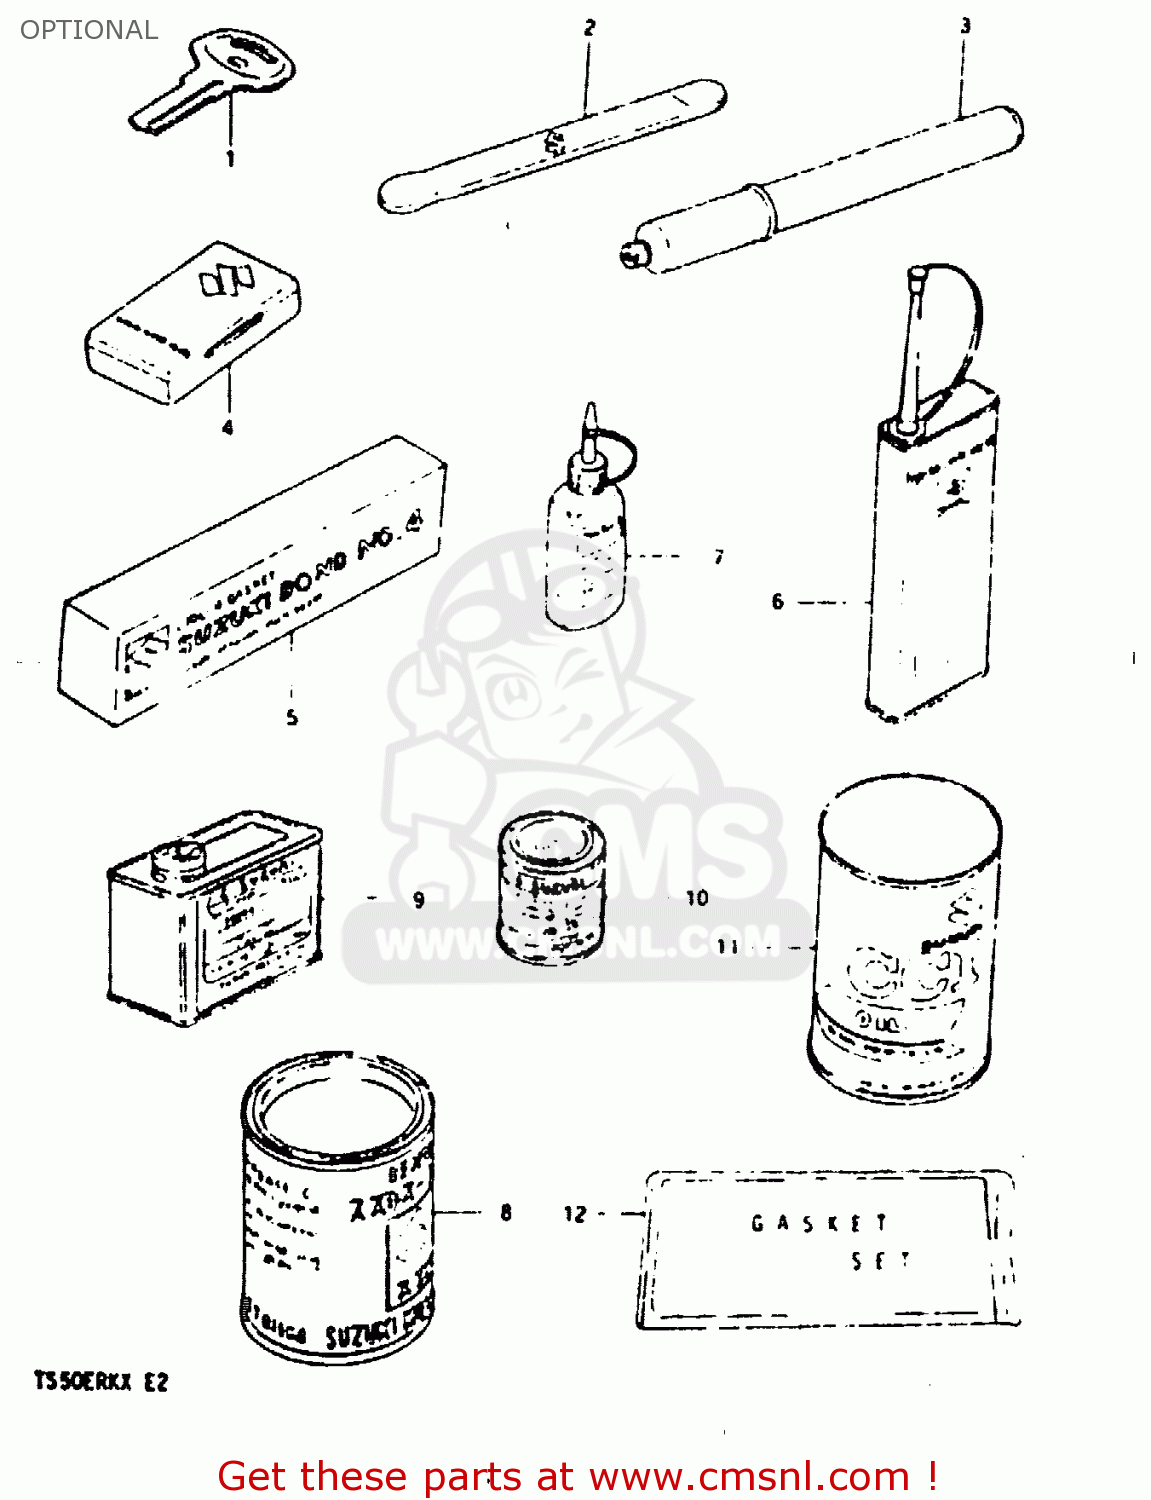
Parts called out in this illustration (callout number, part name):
1	KEY,BLANK
2	LEVER,TIRE
3	INFLATOR, AIR
4	TUBE REPARING TOOL
5	BOND 1104
6	THREAD LOCK NO.1401 CLEAR 200G
7	THREAD LOCK NO.1303B PURPL 50G
8	GREASE(C)EP2 LITHIUM 150G
9	PAINT (BLACK)
10	PAINT,BLACK
11	CCI OIL
12	GASKET SET (MCA)
